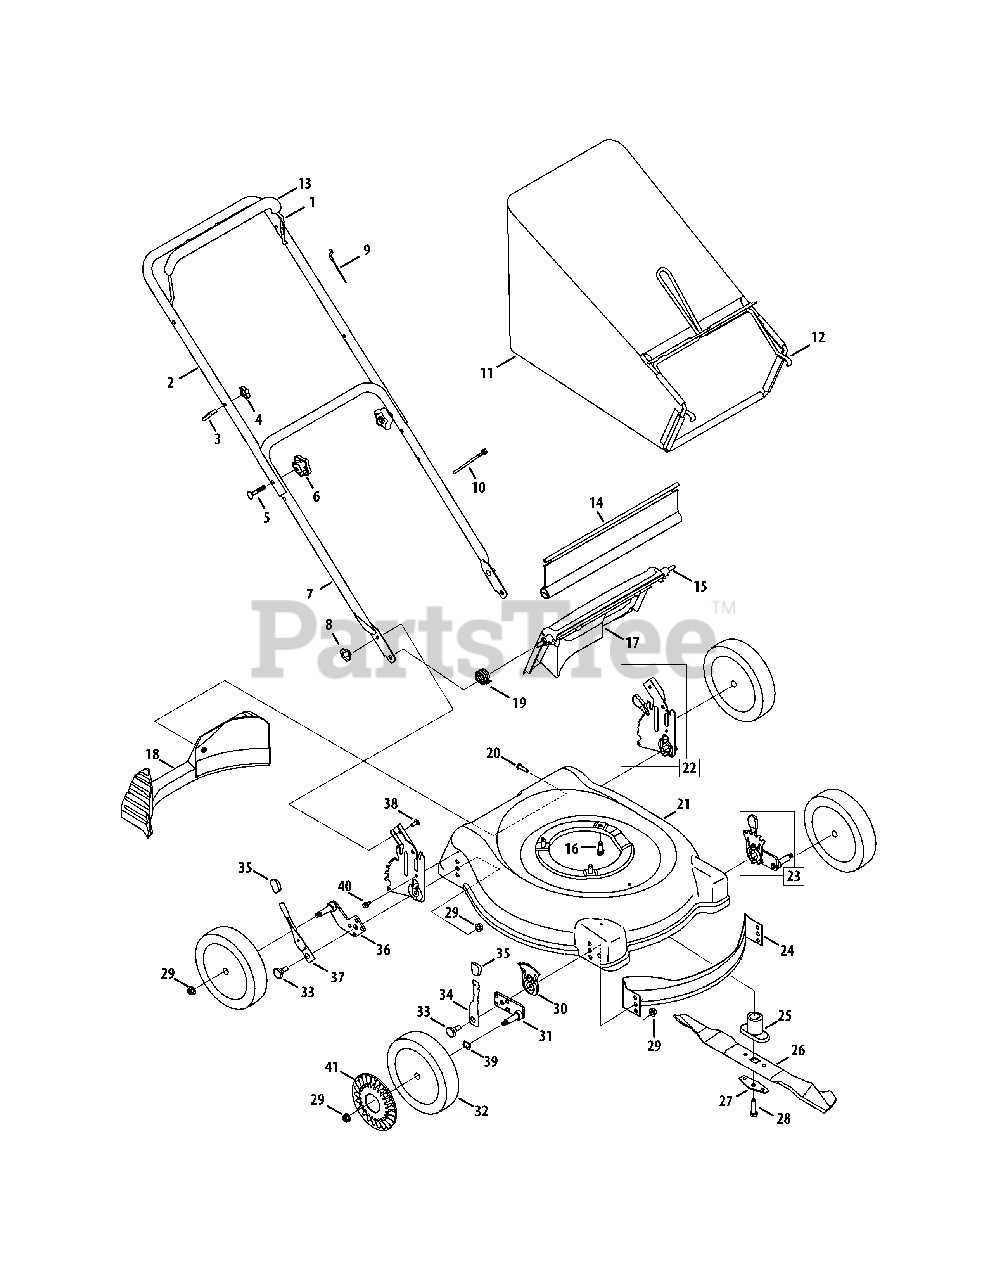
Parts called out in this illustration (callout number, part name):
1	Blade Control
2	Upper Handle
3	Rope Guide
4	Wing Nut, 1/4-20
5	Carriage Bolt, 5/16-18 x 2
6	Hand Star Knob
7	Lower Handle
8	Wing Nut, 1/4-20
9	Control Cable - 40"
10	Cable Tie
11	Grass Bag
12	Grass Bag Frame
13	Bail Cover
14	Trailshield
15	Rear Door Pivot Rod
16	TT Screw, 3/8-16 x 1
17	Rear Discharge Door
18	Rear Baffle
19	Torsion Spring RH
20	Screw, 1/4-15 x 1.00
21	Deck 21 inch
22	Handle Bracket Assy - RH
22	Handle Bracket Assy - LH
23	Ht. Adj. Assy. Frt - LH
23	Ht. Adj. Assy. Frt - RH
24	Front Baffle
25	Blade Adapter, #6 x 2.15
26	Standard Blade
26	Mulch Blade
27	Blade Bell Support
28	Hex Screw, 3/8-24 x 2.50
29	Flange Lock Nut, 3/8-16
30	Height Adjustment Plate
31	Pivot Arm Assy RH
31	Pivot Arm Assy LH
32	Wheel, 8 x 2.125
33	Shoulder Screw
34	Spring Lever
35	Height Adjustment Knob
36	Pivot Arm Assembly - RH
36	Pivot Arm Assembly - LH
37	Spring Lever
38	Carriage Bolt, 1/4-20
39	Wave Washer
40	Screw, 1/4-20 x .625
41	Hub Cap
